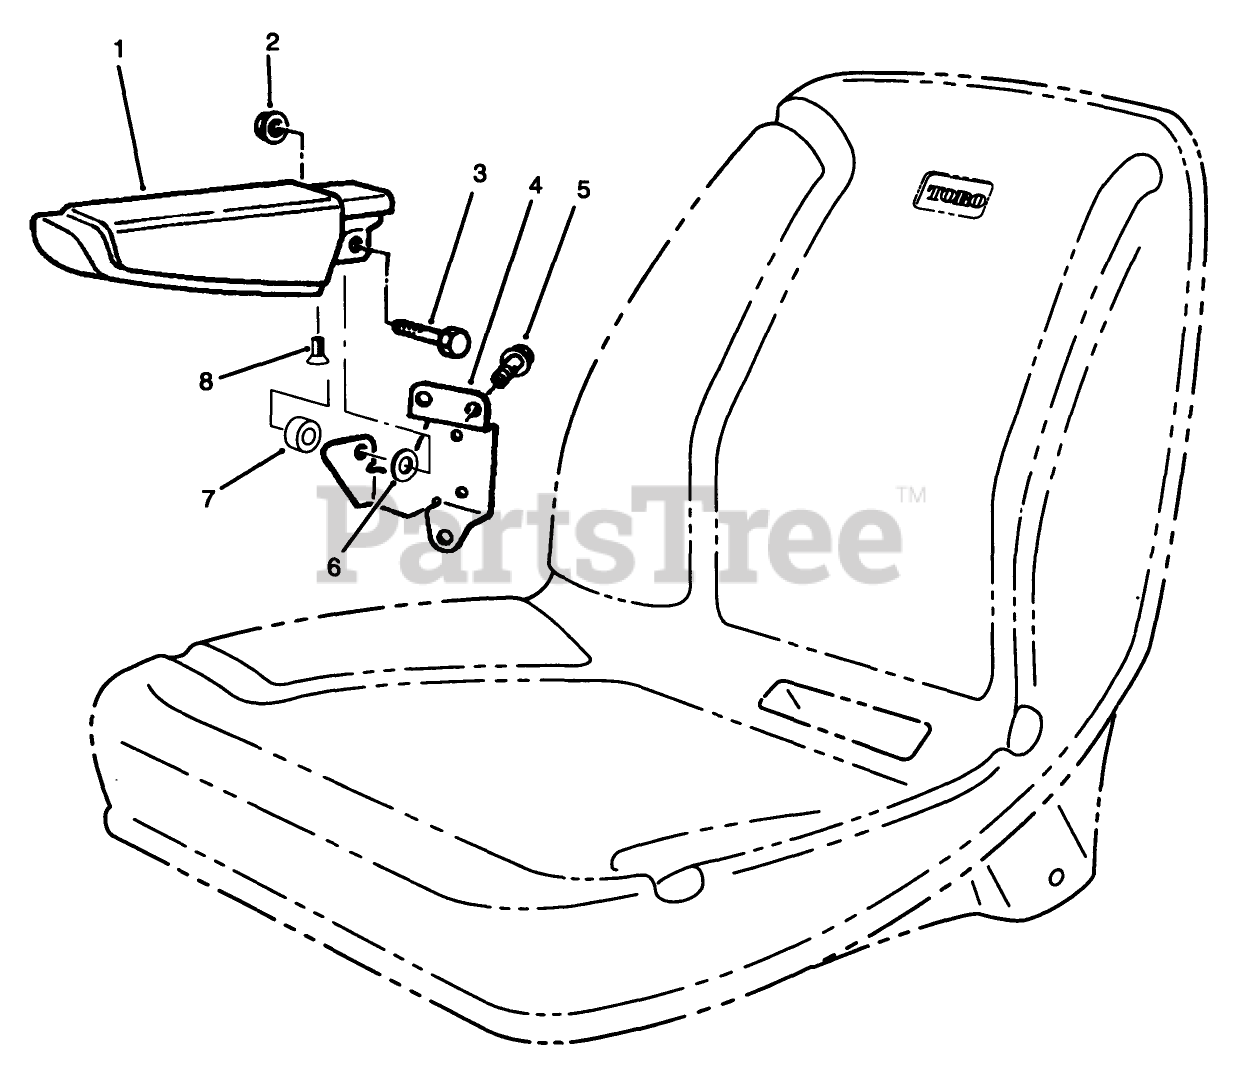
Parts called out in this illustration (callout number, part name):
1	ARMREST
2	NUT-HF
3	SCREW-HH
4	BRACKET-ARM, RH
5	SCREW-HHF
6	WASHER-FLAT
7	SPACER
8	SCREW
